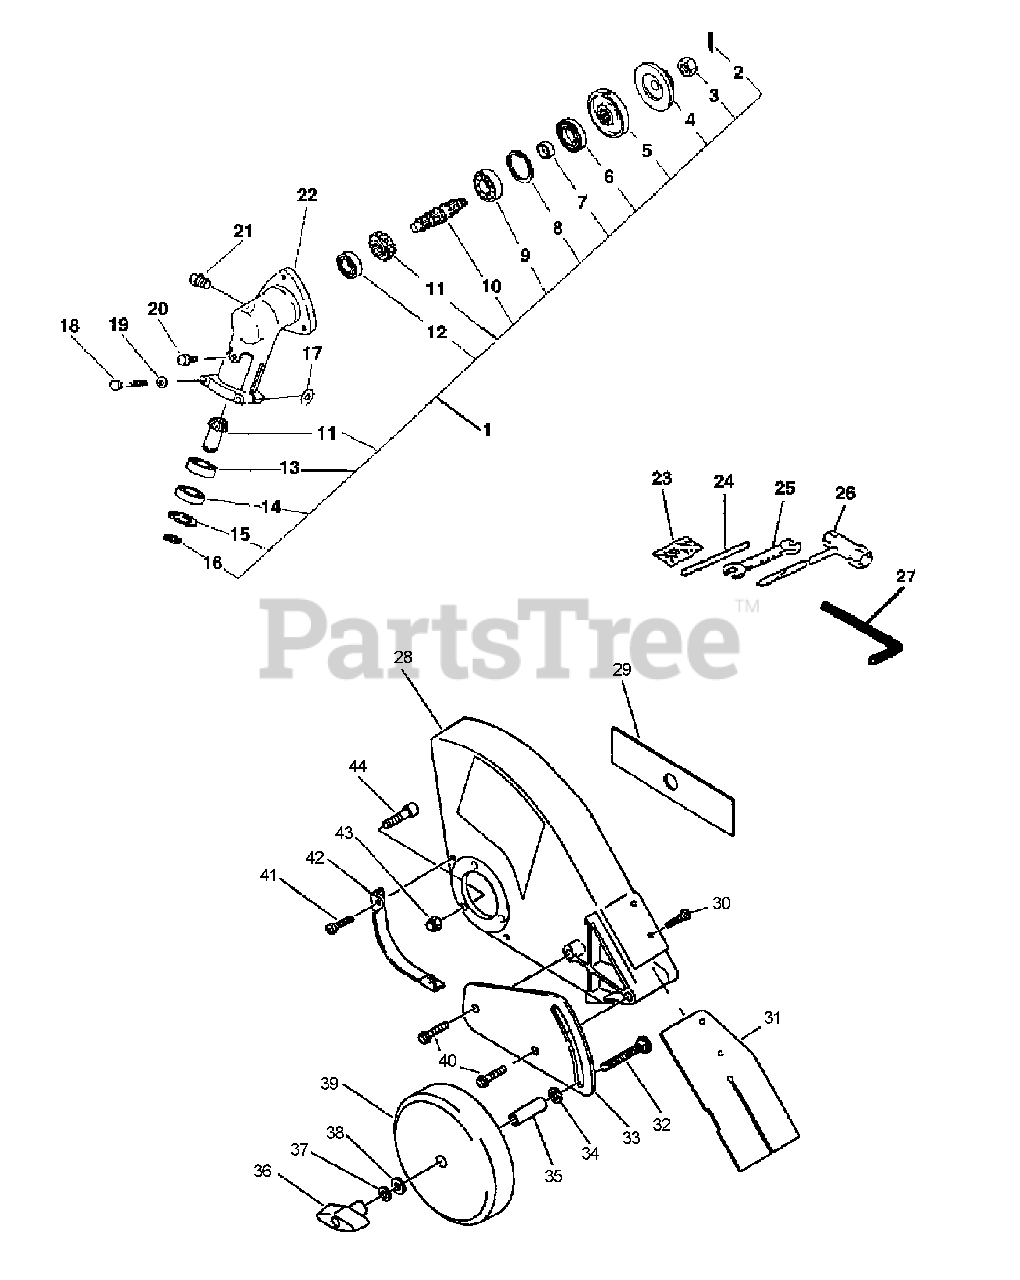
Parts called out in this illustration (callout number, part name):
1	GEAR CASE ASSY
2	PIN, SPLIT - 2X22
3	NUT - 10 -- LEFT HAND
4	ADAPTOR, BLADE - LOWER
5	ADAPTOR, BLADE - UPPER
6	SEAL, OIL
8	RING, RETAINING - 32
9	BEARING, BALL - 6201
10	GEAR - SHAFT
11	GEAR SET - BEVEL
12	BEARING, BALL - 609
13	BEARING, BALL - 6900
14	BEARING, BALL - 6900Z
15	RING, RETAINING - 22
16	RING, RETAINING - 12
18	WASHER - 5
19	BOLT - 5X35
20	BOLT - 5X8
21	SCREW - 5X10
22	CASE, GEAR
23	PIN, SPLIT - 2X22
24	LOCKING TOOL
25	SPANNER - 8X10mm
26	T-WRENCH - 17X19mm
27	HEX KEY - 3mm
28	SHIELD, DEBRIS
29	BLADE, EDGER
30	SCREW - 3
31	FLAP, DEBRIS
32	BOLT - CARRIAGE
33	BRACKET, WHEEL
34	WASHER - 10
35	COLLAR - 12
36	WINGNUT - 5/16-18
37	LOCKWASHER - 8
38	WASHER - 8
39	WHEEL - 6X1.5
40	BOLT - 8
41	SCREW - 4X16
43	LOCKNUT - 5
44	SCREW - 5X22
